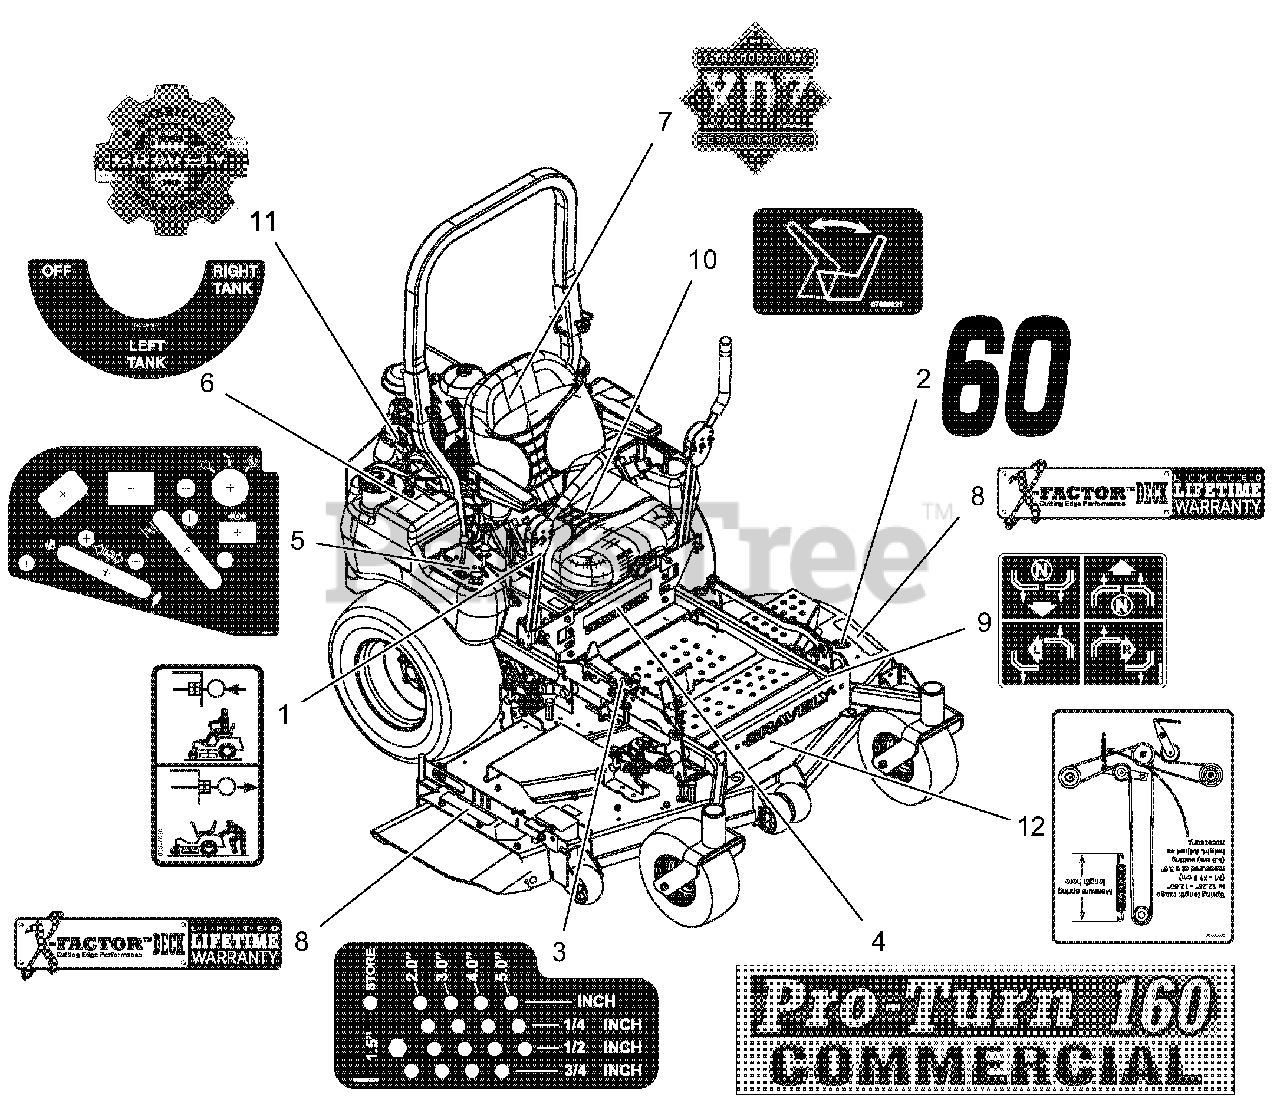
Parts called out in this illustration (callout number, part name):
1	DECAL, TRANSMISSION DISCONNECT
2	DECAL, 60"
3	DECAL, HEIGHT OF CUT
4	DECAL, PRO-TURN 160
5	DECAL, CONTROL PANEL
6	DECAL, FUEL VALVE
7	DECAL, XDZ
8	DECAL, X-FACTOR DECK
9	DECAL, INSTRUCTIONAL - STEERING
10	DECAL, SEAT RELEASE
11	DECAL, GRAVELY HERITAGE-LARGE
12	DECAL, BELT DIAGRAM 60"
